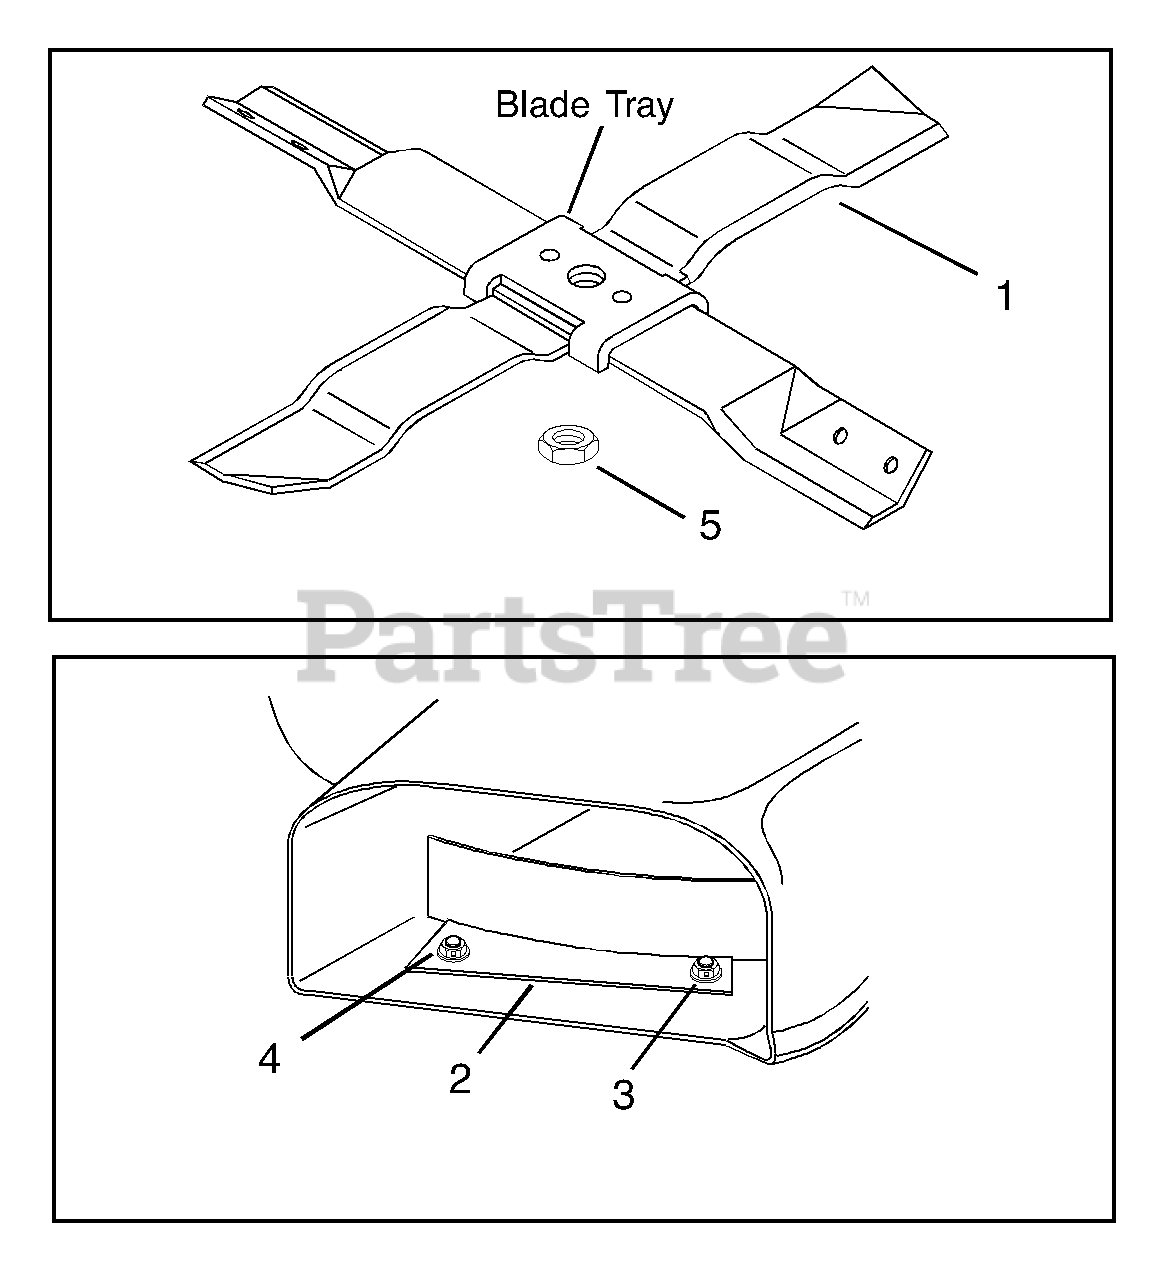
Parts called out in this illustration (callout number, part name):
1	Mulching Blade
2	Mulching Cover
3	Bolt-Round Head Square Neck .25-20 x .75
4	Nut-Locking-Center .25-20
5	Nut-Locking-Jam-Nylon .75-10
